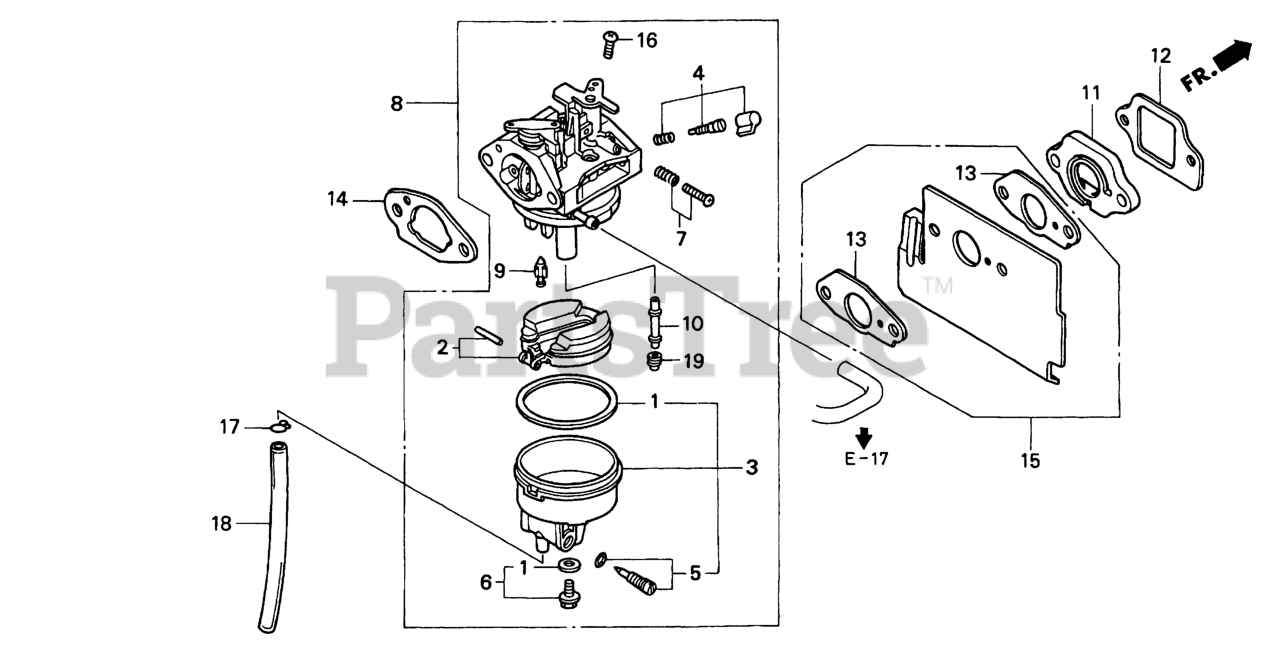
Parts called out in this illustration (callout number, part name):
1	GASKET SET
2	FLOAT SET
3	CHAMBER SET, FLOAT
4	SCREW SET (CARBURETOR NO.)
5	SCREW SET, DRAIN (ADVENTURE GREEN) (CARBURETOR NO.)
6	SCREW SET B
6	SCREW SET
7	SCREW SET (THROTTLE STOP) (CARBURETOR NO.)
8	CARBURETOR ASSY. (BB61J B)
9	VALVE, FLOAT (CARBURETOR NO.)
10	NOZZLE, MAIN (CARBURETOR NO.)
11	INSULATOR, CARBURETOR
12	GASKET, INSULATOR
13	GASKET, CARBURETOR
14	GASKET, CARBURETOR (Honda Code 5580253). (CHOKE SIDE)
15	GUIDE, AIR
16	SCREW, PAN (5X6)
17	CLIP, TUBE (B6.5)
18	BULK HOSE, VINYL (4X7X8000) (95003-07(95003-07001-60M) (CARBURETOR NO.)
19	JET, MAIN (#60) (Honda Code 0635474). (CARBURETOR NO.)
19	JET, MAIN (#62) (Honda Code 0635482). (CARBURETOR NO.)
19	JET, MAIN (#65) Use up to Engine SN BB30A D.
